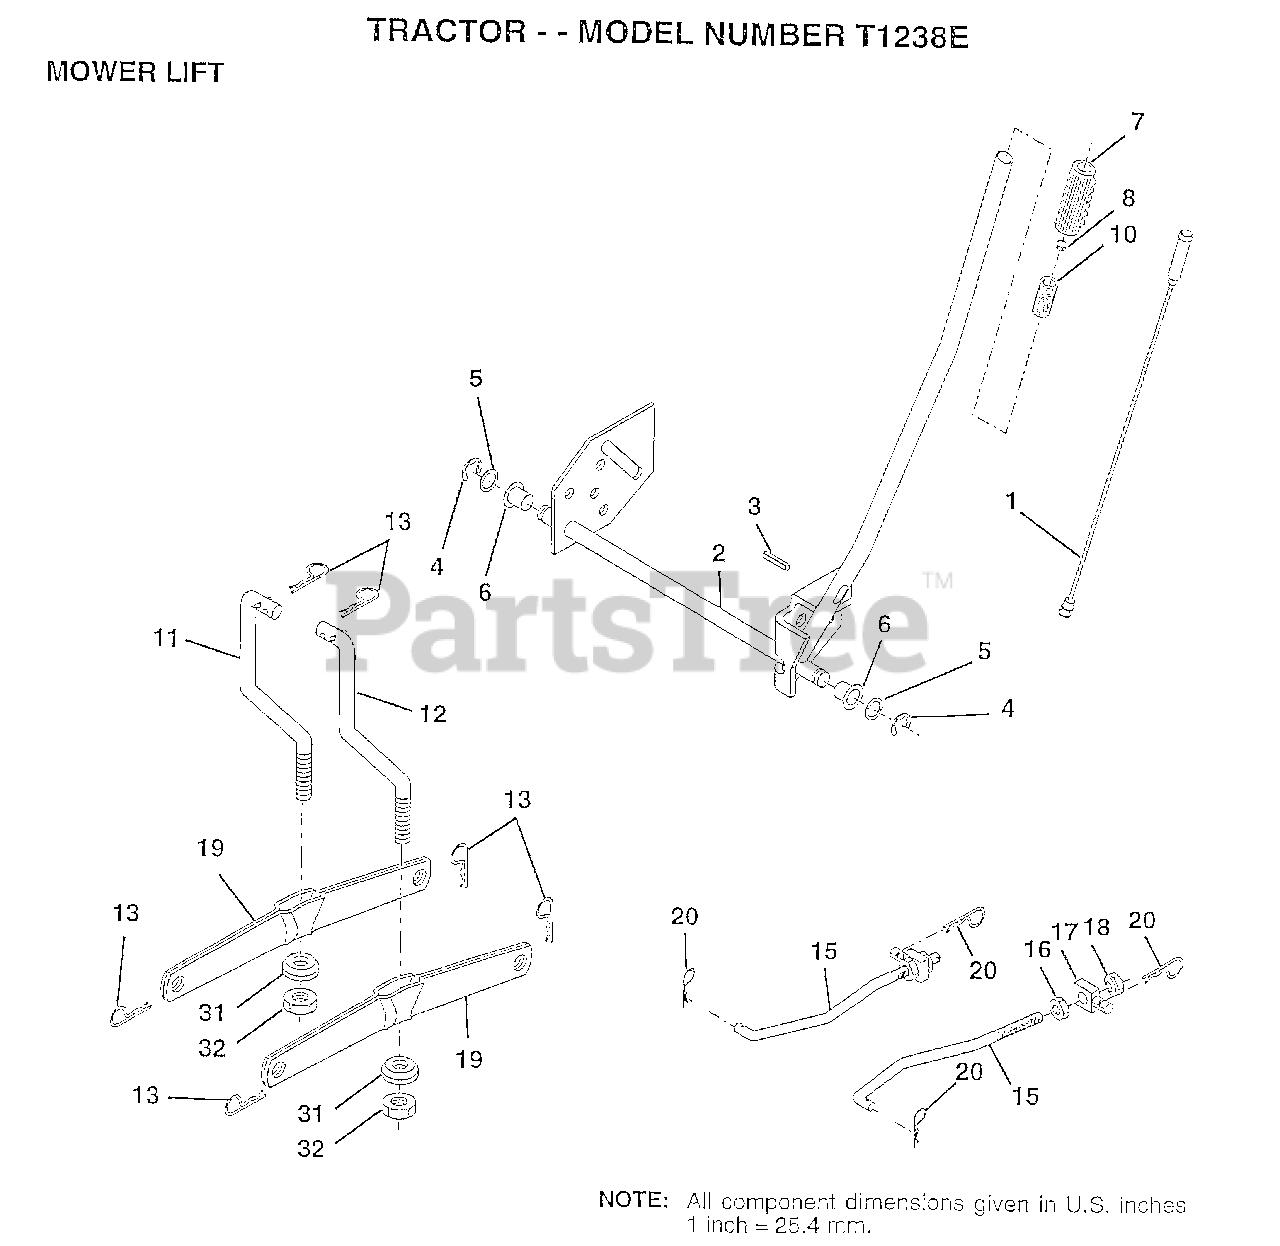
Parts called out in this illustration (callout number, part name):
1	WIRE ASM
3	PIN-GROOVE LT
5	WASHER
6	NYLON BEARING
7	GRIP
15	LINK.FRONT
16	NUT
17	TRUNION
18	NUT.LK.W/WSH.1/2.
19	ARM SUSP REAR
20	RETAINER.SPRING
31	BEARING PVT LH
32	NUT.CROWNLOCK.3/8
